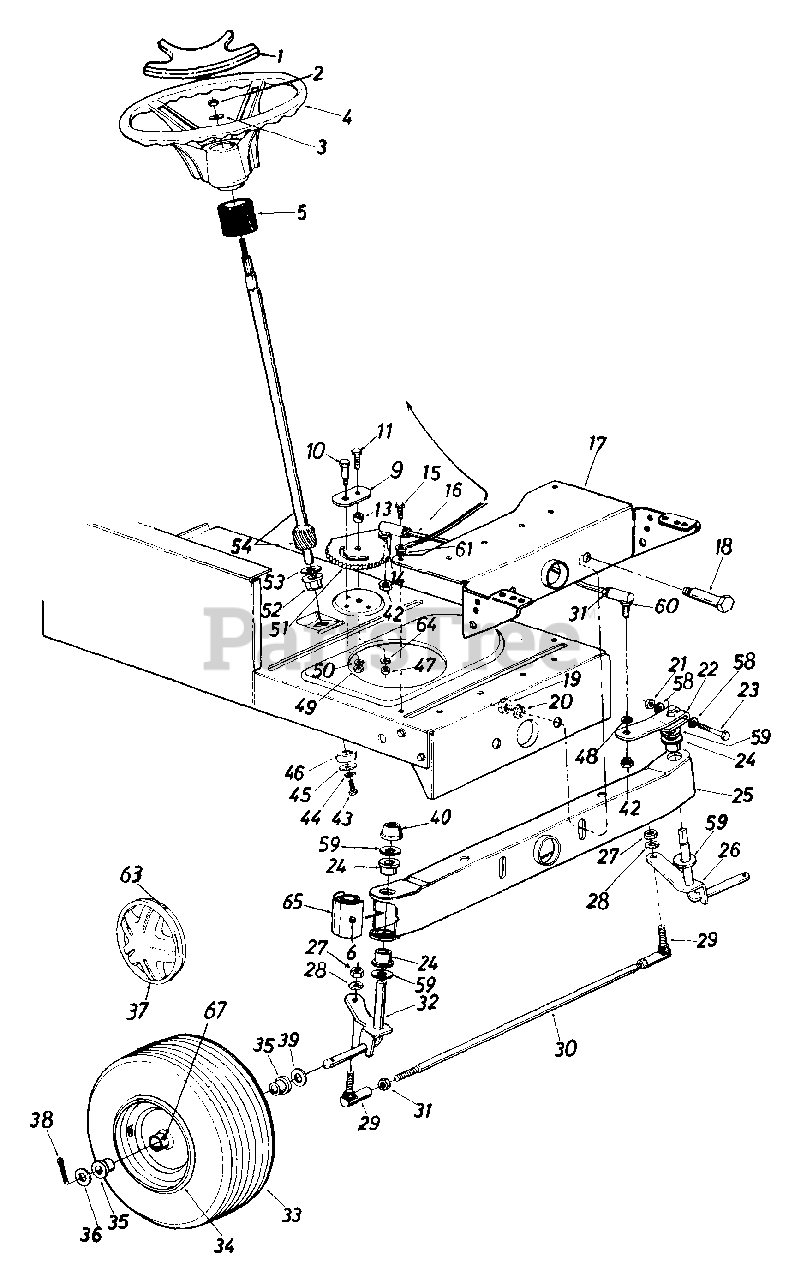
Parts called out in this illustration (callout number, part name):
1	Steering Wheel Cap
2	Hex L-Nut 5/16-24 Thd.
3	Belleville Wash..345" I.D.
4	Steering Wheel
5	Steering Bellow - 9"
6	Grease Fitting
9	Retainer Plate
10	Shoulder Bolt .437" Dia. x .35" Lg.- 5/16-18 Thd.
11	Hex Bolt 3/8-24 x 1.0" Lg. (Grade 5)
13	Spacer .380" I.D. x .625" O.D. x .227
15	Hex Wash. Hd. Self-Tap Scr.
16	Steering Drag Link
18	Shoulder Bolt .498" Dia. x 2.04" Lg.- 3/8-16 Thd.
19	Hex Nut 3/8-16 Thd.
20	L-Wash. 3/8" I.D.
21	Hex L-Nut 5/16-24 Thd.
22	Steering Arm Front Axle
23	Hex Bolt 5/16-24 x 2.00" Lg. (Grade 5)
24	Hex Flg. Brg..632 I.D.
26	Front Axle Ass'y.- L.H.
27	Hex Nut 3/8-24 Thd.
28	L-Wash. 3/8" I.D.
29	Ball Joint 3/8-24 Thd.
31	Hex Jam Nut 3/8-24 Thd.
32	Front Axle Ass'y.- R.H.
36	Fl-Wash..635" I.D. x 1.59" O.D.
37	Front Wheel Hub Cap
38	Cotter Pin 1/8" Dia. x 1.25"
39	Fl-Wash..640" I.D. x 1.24" O.D.
40	Push Cap 5/8" Dia. Rod
42	Hex Jam Nut 3/8-24 Thd.
43	Hex L-Bolt 5/16-18 x .62"
44	L-Wash. 5/16" I.D.
45	Fl-Wash..33" I.D. x 1.25" O.D.
46	Spacer (Plastic)
47	Hex Cent. L-Nut 3/8-24 Thd.
48	L-Wash. 3/8" I.D.
49	Hex Cent. L-Nut 5/16-18 Thd.
50	L-Wash. 5/16" I.D.
51	Steering Gear Segment
52	Hex . Flg. Brg..634 I.D.
53	Fl-Wash.
54	Steering Shaft
58	Wave-Wash..32" I.D. x .62" O.D.
59	Fl-Wash.
60	Drag Link Ball Joint 3/8-24 Thd.
61	Ext. L-Wash. 5/16" I.D.
63	Spring Clip
64	Bell-Wash..39" I.D. x 1.38" O.D.
65	Pivot Bar End Cap
67	Grease Fitting
